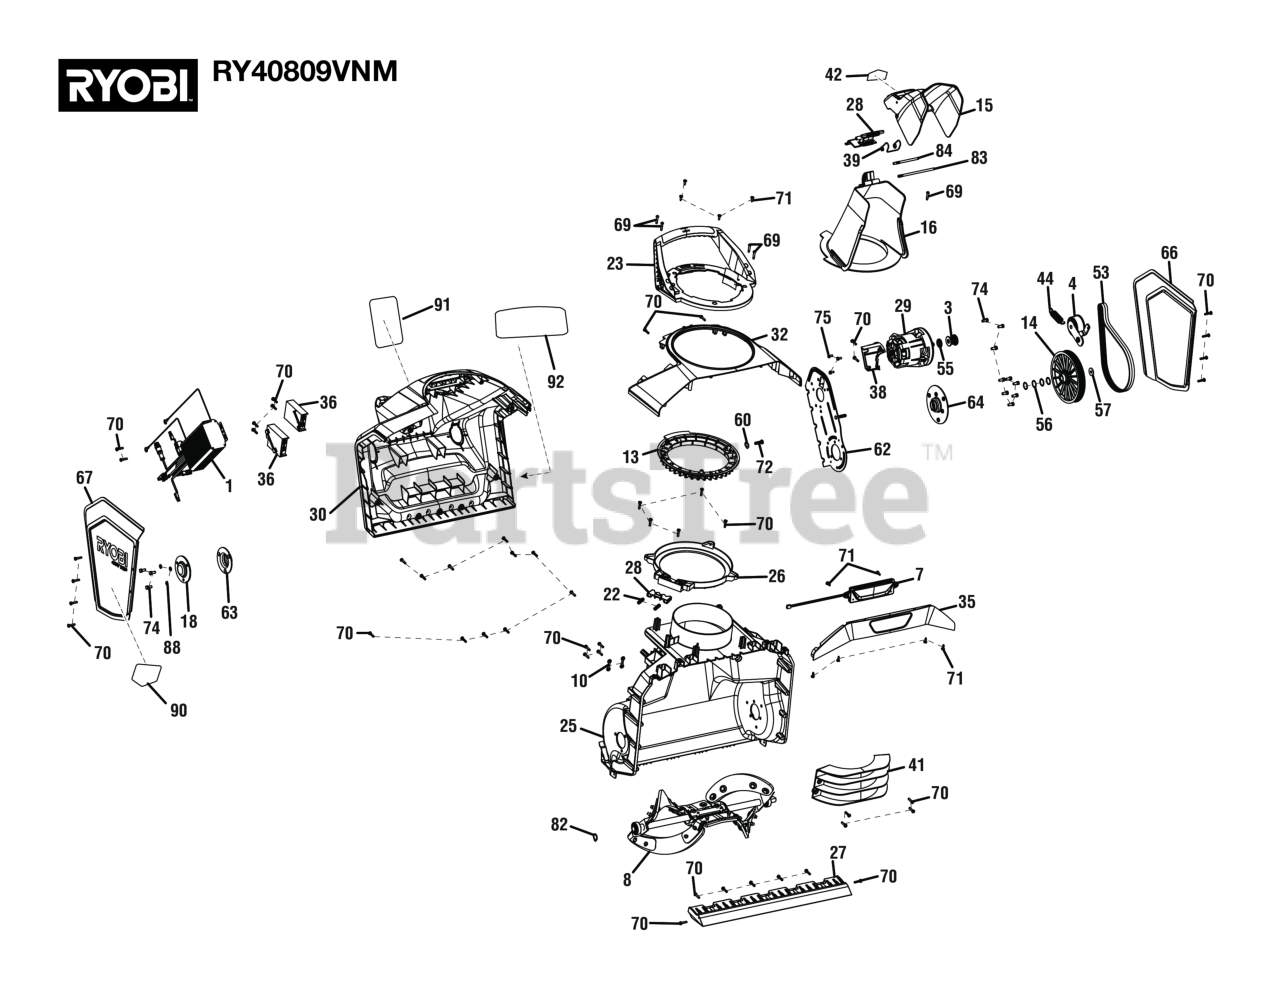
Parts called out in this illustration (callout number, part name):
1	Motor Controller
3	Motor Pulley
4	Sheet Metal Bracket
7	LED Light Assembly
8	Auger Assembly
10	Hold-Down Tab
13	Chute Gear
14	Auger Pulley
15	Chute Deflector With Label
16	Upper Chute
18	Auger Bearing Cover Plate
22	Compression Spring
23	Chute Rotation Assembly
25	Lower Body
26	Chute Rotation Platform
27	Scraper Blade
28	Manual Chute Adjust Detent and Deflector Latch Assembly
30	Rear Cover With Labels
32	Top Cover
35	Front Cover
36	Controller Mounting Assembly
38	Motor Mounting
39	Chute Deflector Spring
41	Lower Chute Neck
42	Chute Warning Icons Label
44	Belt Tensioner Spring
56	Flat Washer (ID15.1 x OD19 x 0.5t)
57	Flat Washer, ID6.6XOD20XT1.6, 65Mn,
60	Wave Washer
62	Motor Mounting Plate
63	Bearing Retainer
64	Bearing Retainer Plate
66	Left Side Cover
67	Right Side Cover With Label
69	Screw (M4 x 20 mm, Philllips -Pan Hd., RY40806VNM)
70	Screw (M4 x 18 mm, T20 Torx Pan Hd. S.T.)
71	Screw (M4.2 x 12 mm, T20 Torx Pan Hd.)
72	Screw (M6 x 20 mm, T27 Torx Button Hd.)
74	Screw (M5 x 12 mm, Hex Hd.)
75	Screw, M4X0.7, SCM435, Black Zinc Plated
83	Pin (Deflector)
84	Pin (Latch)
88	Washer (OD9.8 x ID5.3 x 0.8t)
90	Danger Label (No Hands/Feet)
91	Icons and EN/FR Danger Label
92	Data/Caution/SP Danger Label
